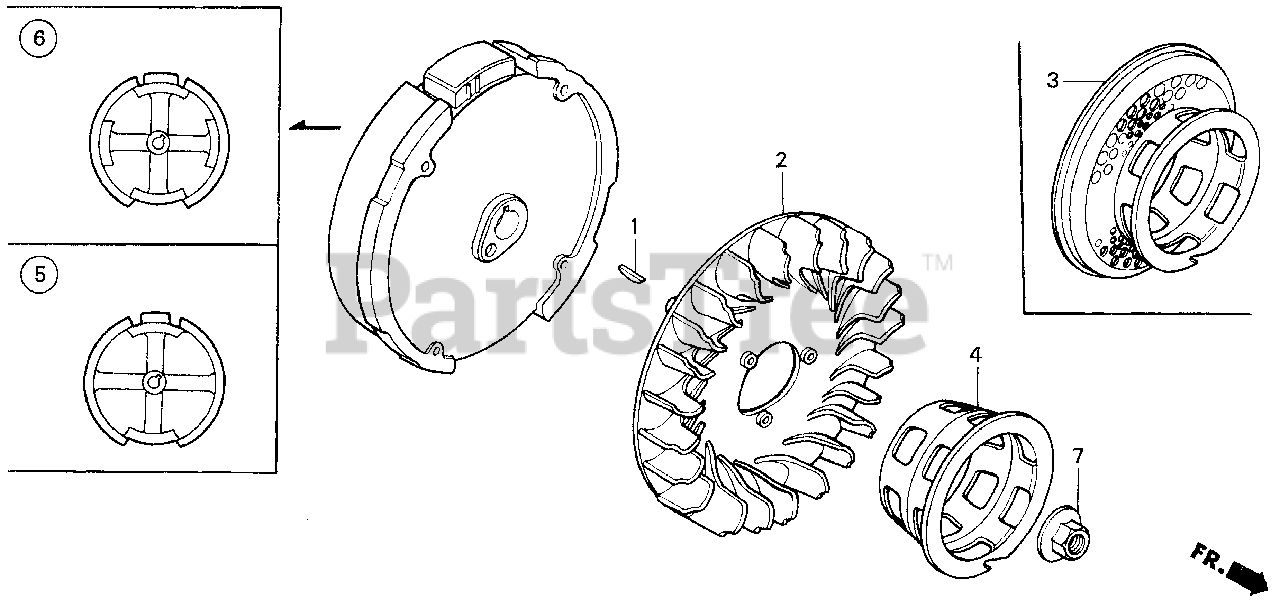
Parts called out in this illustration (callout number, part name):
1	KEY, SPECIAL WOODRUFF (25X18)
2	FAN, COOLING
3	PULLEY, STARTER
5	FLYWHEEL
7	NUT, SPECIAL (14MM)
